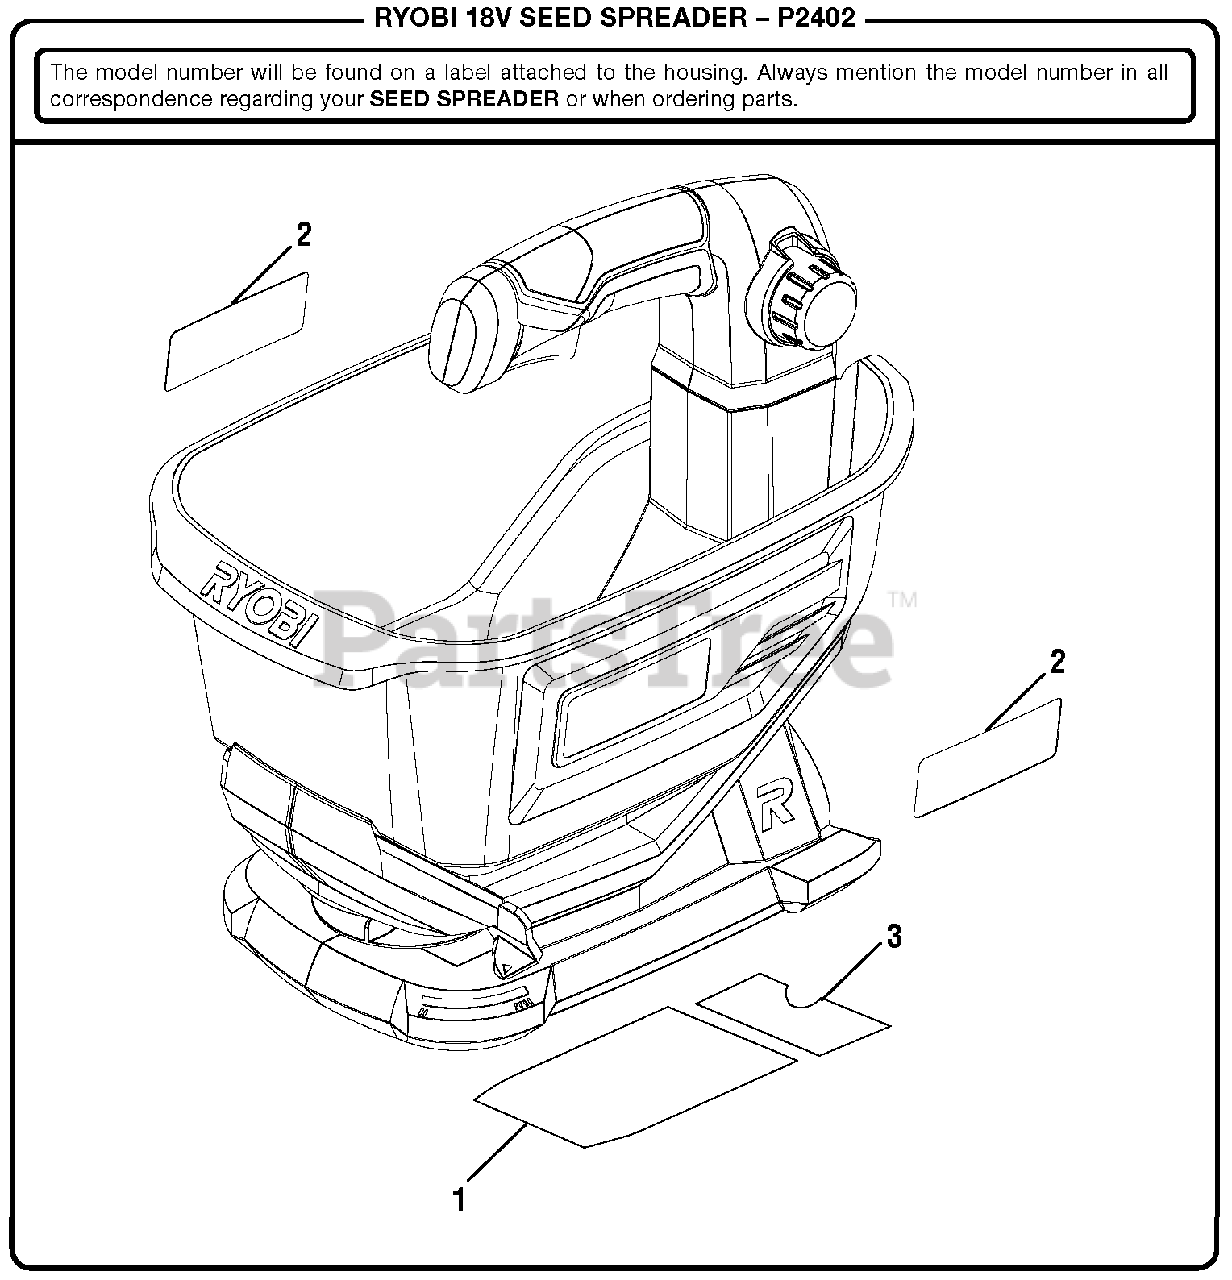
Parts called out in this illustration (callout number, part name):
1	Data Label
2	Logo Label
3	Icon Label
